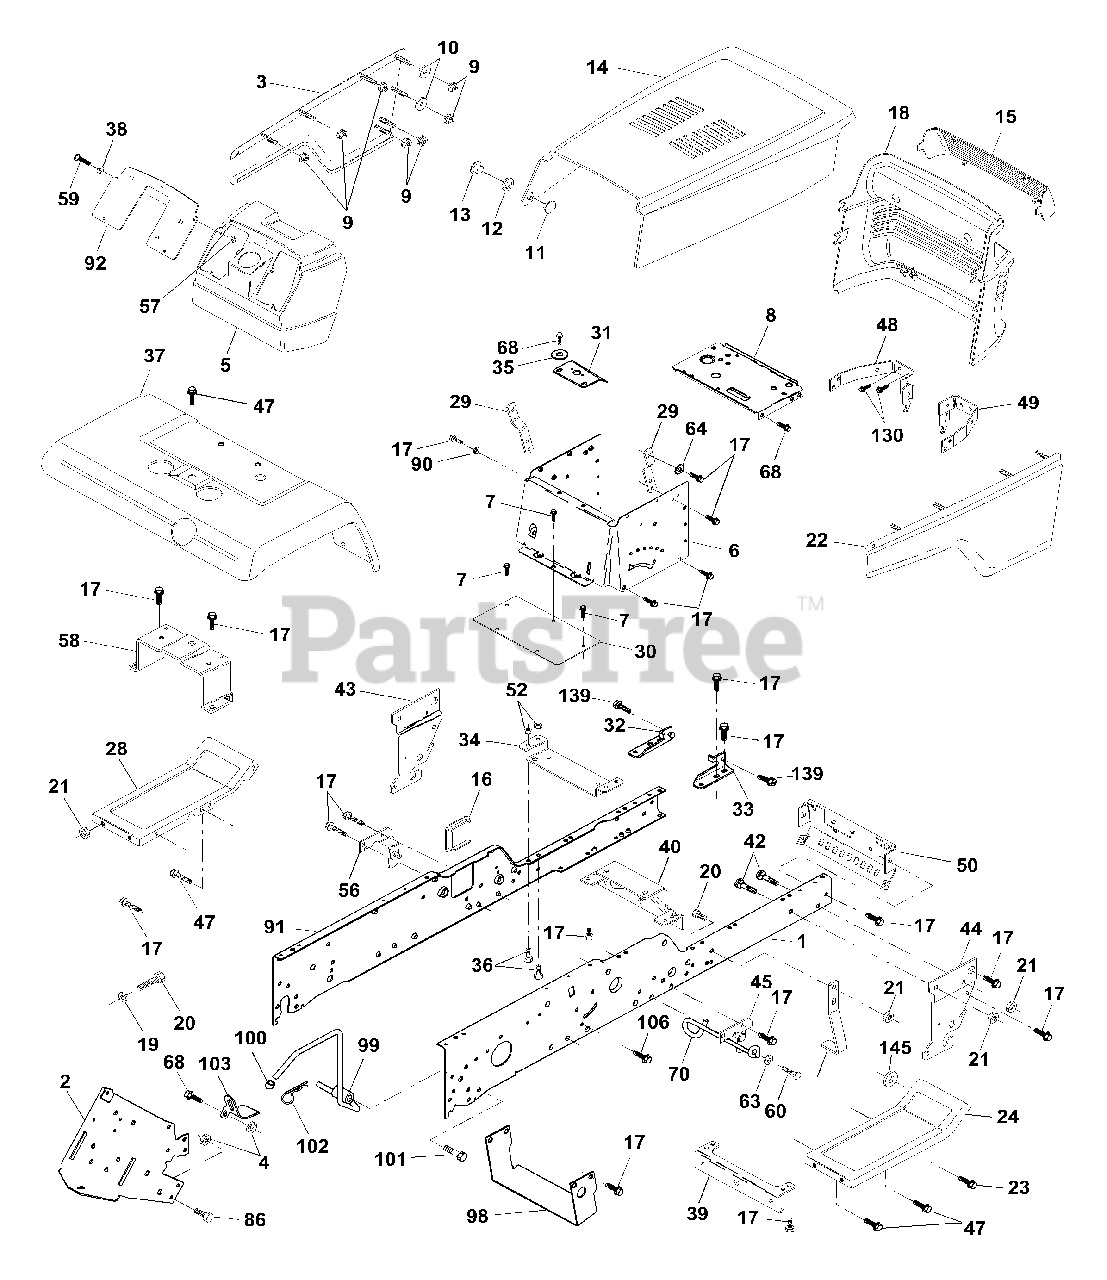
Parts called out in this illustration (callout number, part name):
1	Rail, Frame RH
2	Drawbar, Gt
3	Panel Asm., Side LH
4	Nut, Lock Hex 7/16 Unc
5	Dash, Plastic Black
6	Dash, Lower Vgt One-Piece
7	Screw, Thd Cut 1/4-20 x 1/2
8	Support, Battery
9	Nut, Pal
10	Washer 9/32 x 1-1/4 x 16
11	Rivet Ratchet Male
12	Washer Nylon
13	Rivet Ratchet Female
14	Hood, Asm Pnt
15	Lens, Clip Asm, Bar, Clear
16	Cover, Access
17	Screw 3/8-16 x 3/4
19	Washer 13/32 x 13/16 x 12 Ga.
20	Bolt, Fin Hex 3/8-16 x 1
21	Nut, Crownlock 3/8-16 Unc
22	Panel Asm., Side RH
23	Screw, Thdrol 3/8-16 x 1 Ty-Tt
24	Footrest, RH
28	Footrest, LH
29	Bracket, Support Dash
30	Saddle, Hydro 1995
31	Bracket Support
32	Bracket Asm., Frame Pivot Lh
33	Bracket Asm., Frame Pivot Rh
34	Bracket, Engine Support Rear
35	Washer 11/32 x 11/16 x 16 Ga.
36	Bolt, Fin Hex 5/16-18 x 3/4
38	Washer 9/32 x 3/4 x 16
39	Bracket, Axle Front
40	Bracket, Support Axle/Engine
42	Bolt RDHD SQNK 3/8-16unc x 1
43	Bracket, Spnsn Front Lh
44	Bracket, Spnsn Front Rh
45	Bracket Asm., Susp Chassis Rh
47	Screw Thdrol 3/8-16 x 1/2
48	Bracket Asm Hood Lh
49	Bracket Asm Hood Rh
50	Bracket, Chassis Front
52	Nut, Crownlock 5/16-18
56	Bracket Asm., Susp Chassis Lh
57	Nut Keps Blk Hex 1/4-20
58	Bracket Asm., Fender
59	Screw Mach Cr 1/4-20 x 3/4
60	Screw Thdrol 3/8-16 x 1-1/4
63	Washer 13/32 x 1 x 14 Ga.
64	Washer Serrated Disc 13/32 x 1
68	Screw, Thdrol 5/16-18 x 1/2
70	Guide, Belt Mid Span
84	Stop, Over Center Mower
86	Bolt, Fin Hex 7/16-14 Unc x 1
90	Washer, Lock External Tooth 3/8
91	Rail, Frame Lh
92	Plate, Silkscreen Dash
98	Bracket, Chassis Skid
99	Rod By Pass
100	Cap By Pass Rod
101	Screw Thdrol 3/8-16 x 1-3/4
102	Retainer, Spring
103	Lock By Pass/Bracket
106	Screw, Thdrol Hex Head Zinc Mwr
130	Screw Hw Hd Hi-l Lo #13-16 x 3/4
139	Bolt Shoulder 5/16-18
145	Washer Flat 13/32 x 7/8 x 14 Ga.
